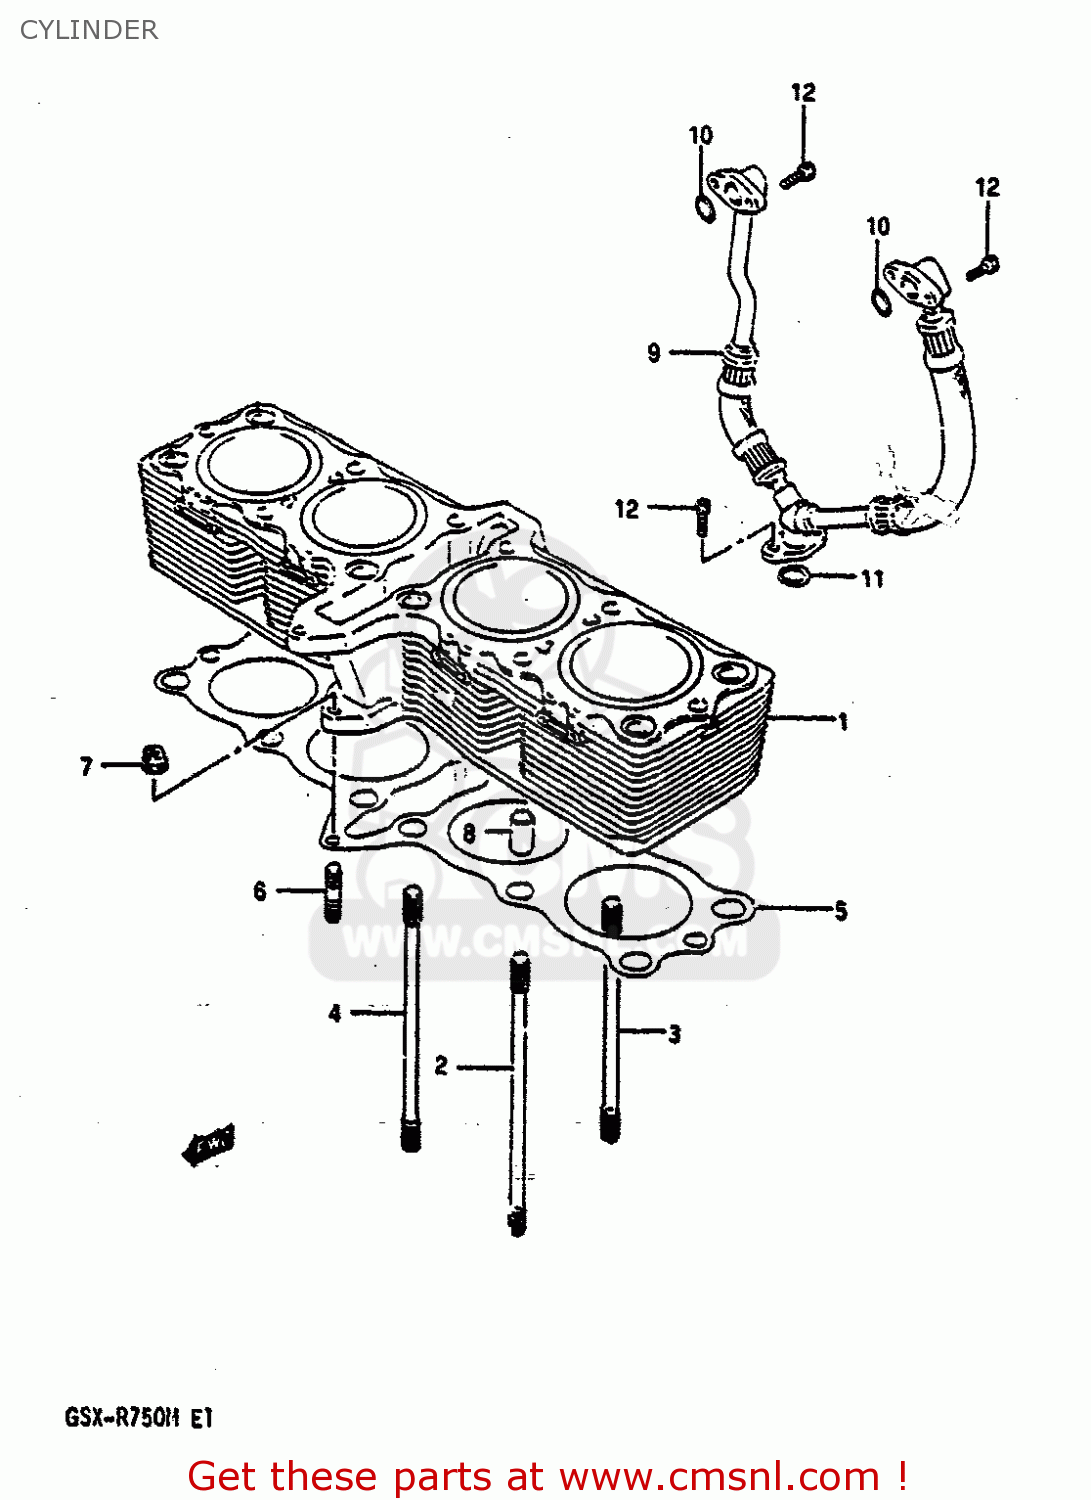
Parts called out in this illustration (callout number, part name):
1	CYLINDER
2	STUD BOLT (L:150)
3	BOLT,STUD
4	STUD
5	GASKET,CYLINDER (NAS)
6	STUD BOLT L:20
7	NUT 6MM
8	PIN
9	HOSE
10	O RING(D:2.5,ID:13.8)
11	O RING(D:2.4,ID:15.8)
12	BOLT
